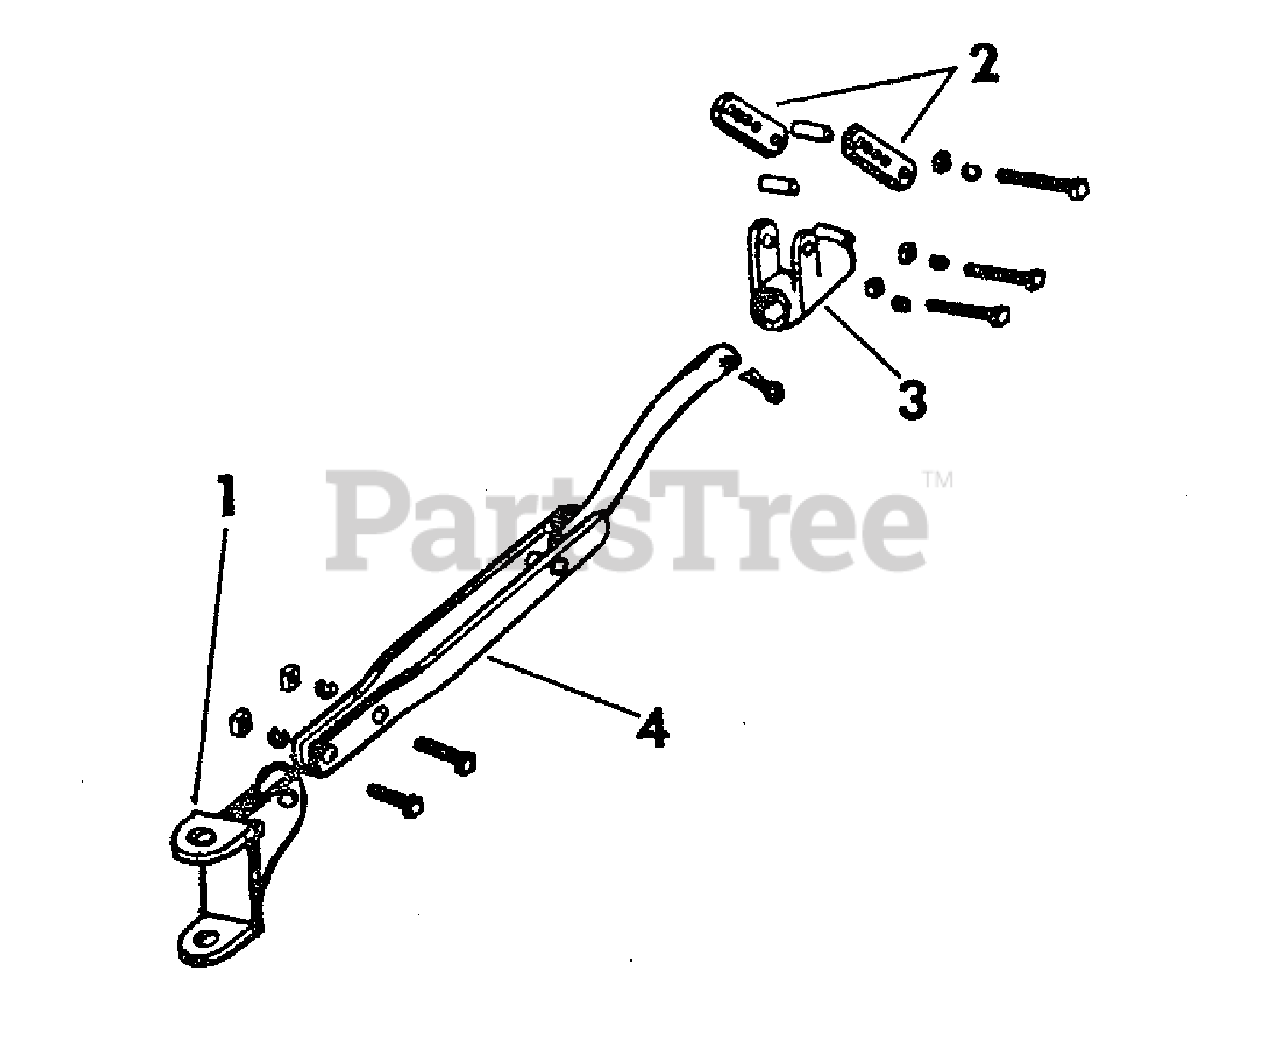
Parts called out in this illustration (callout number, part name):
1	END, Draw Bar
2	LINK, Adjusting
3	HITCH, Lawn Mower
4	TONGUE, Lawn Mower
